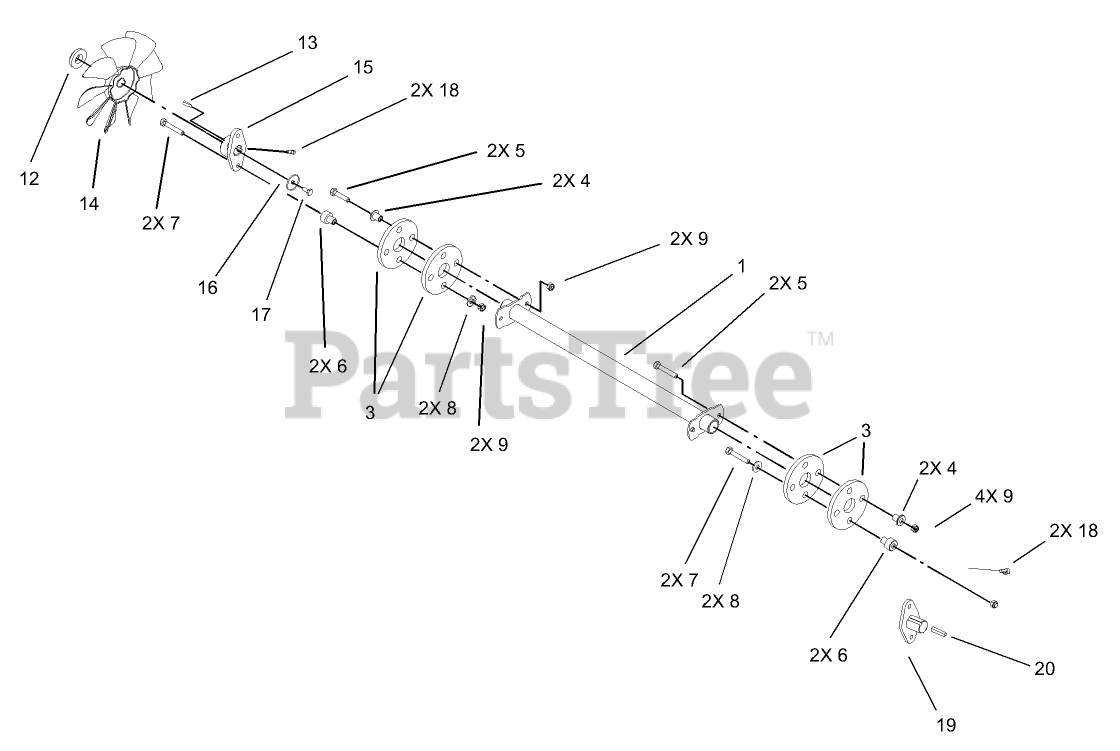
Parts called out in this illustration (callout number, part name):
1	SHAFT-DRIVE
4	SPACER
5	SCREW-HH
6	SPACER
7	SCREW-HH
8	WASHER-FLAT
9	NUT-LOCK, NI
12	SPACER-FAN
13	KEY-WOODRUFF
14	FAN-HYDRO
16	WASHER
17	SCREW-HH
18	SCREW-SET
19	WA - PIN DRIVE
20	KEY-SQUARE
